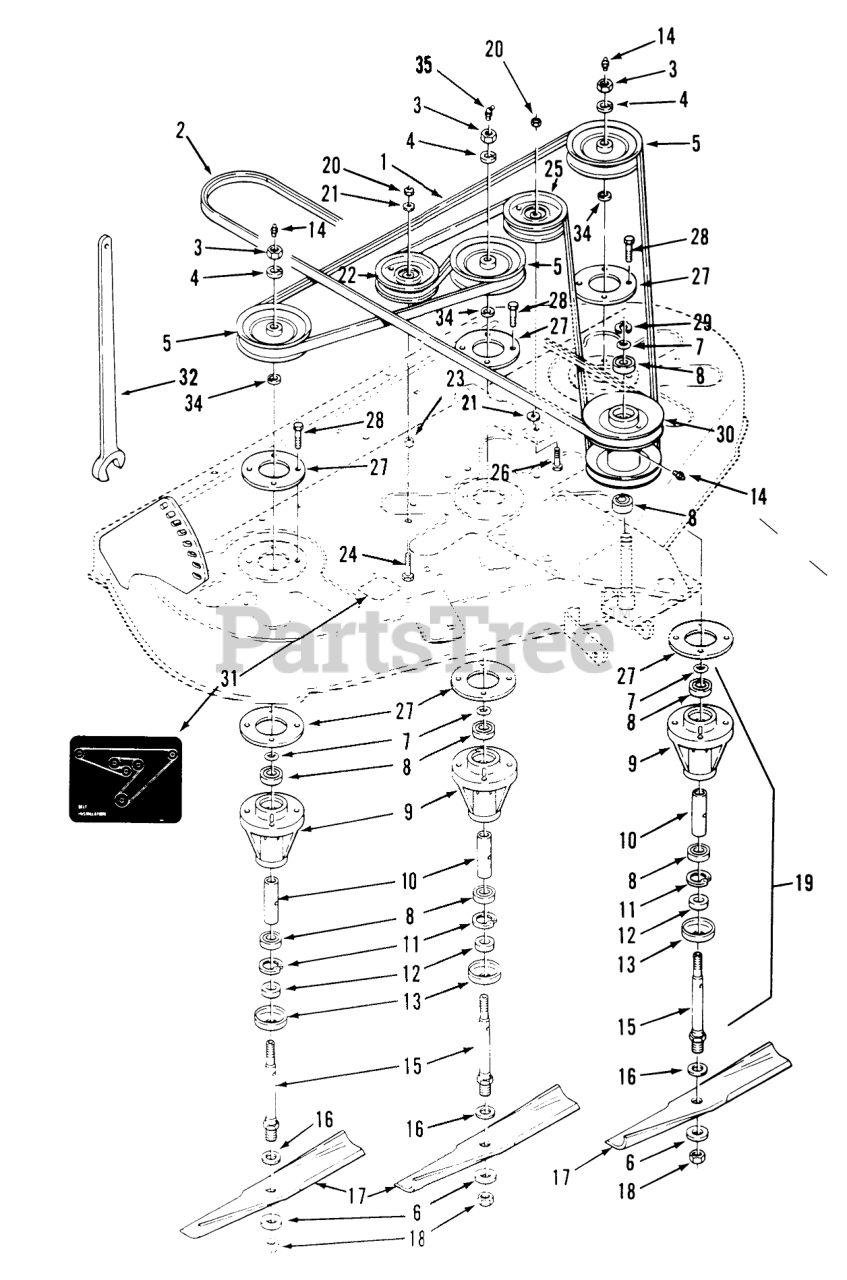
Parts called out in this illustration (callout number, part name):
1	V-BELT
2	V-BELT
3	Nut
4	Lockwasher
5	Pulley
6	Washer
7	O RING
8	BEARING-BALL
9	HOUSING-SPINDLE
11	Ring-Snap
12	SPACER-BLADE
13	CUP-SPINDLE
14	Zerk
15	SHAFT-SPINDLE
16	Washer
17	BLADE KIT
18	Nut
19	Spindle Assembly
20	NUT
21	Washer
22	Pulley-Idler
23	SPACER
24	Bolt
25	PULLEY-FLAT IDLER
26	BOLT
27	SPACER-SPINDLE
28	Bolt
29	RETAINING RING
30	PULLEY-COUNTER SHAFT
31	DECAL-BELT INSTALL
32	Spindle Wrench
34	Washer
35	FITTING-GREASE
